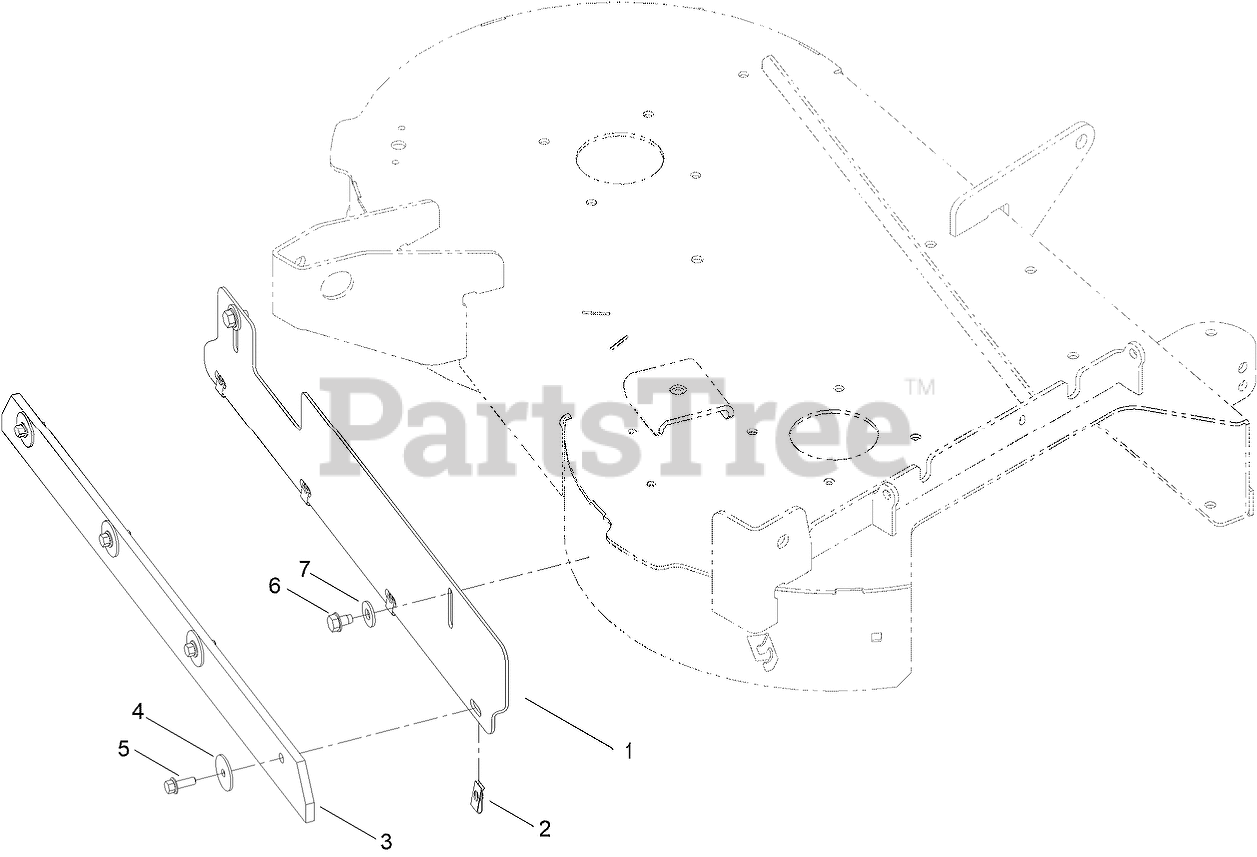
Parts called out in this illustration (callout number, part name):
1	BRACKET-STRIPING, 34" FAB
2	NUT-SPEED
3	WIPER-34 INCH
4	WASHER-FLAT
5	SCREW-HHF
6	SCREW-HWH, THD ROLL
7	WASHER-FLAT
